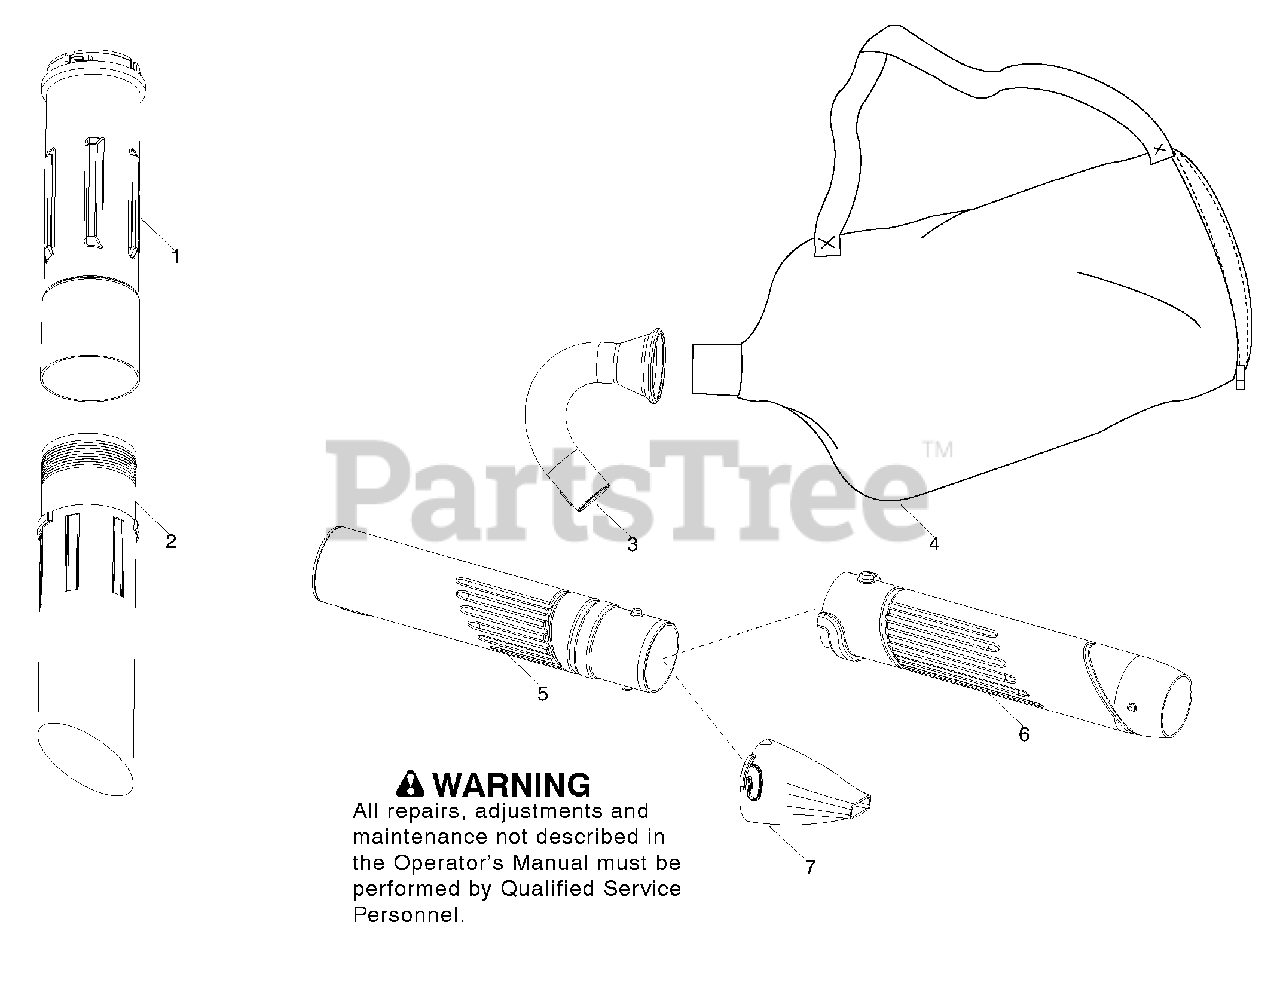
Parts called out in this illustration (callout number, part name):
1	Tube - Upper Vac
2	Tube - Lower Vac
3	Tube - J
4	Assy - Vac Bag
5	Tube - Upper Blower
6	Tube - Lower Blower
7	Nozzle - High Speed
